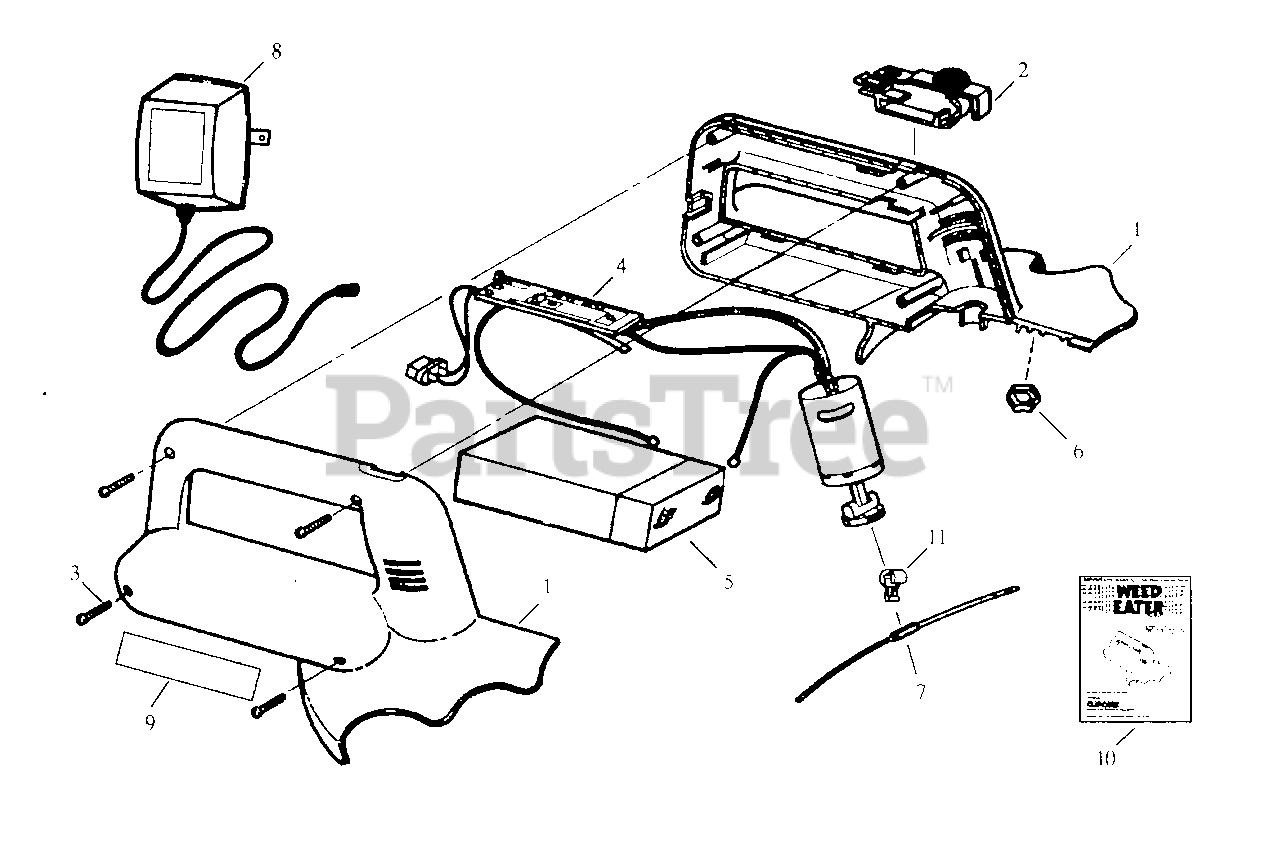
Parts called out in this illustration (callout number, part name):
1	Housing Ass'y.
2	Switch Button
4	Circuit Board/Motor Ass'y.
7	Replacement Line
10	Operators Manual
11	Retainer
